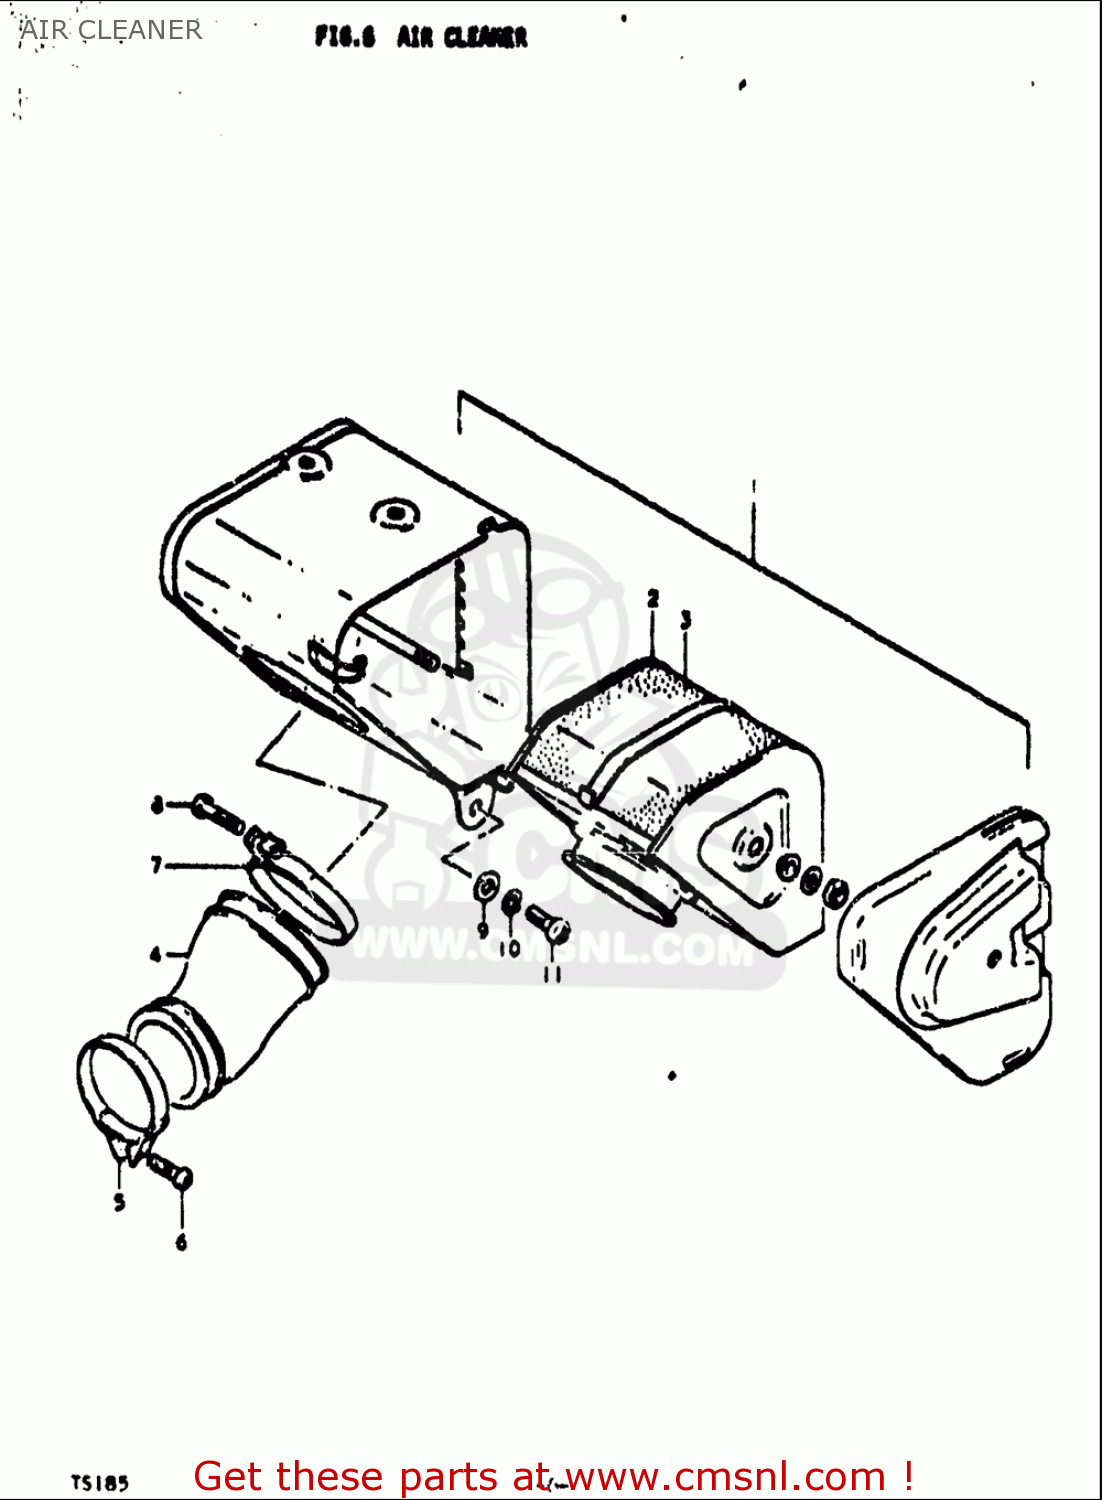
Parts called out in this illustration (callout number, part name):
3	FILTER
4	HOSE,CARBURETOR AIR INLET
5	CLAMP
6	SCREW
7	CLAMP
8	SCREW
9	WASHER
10	WASHER,LOCK
11	SCREW
